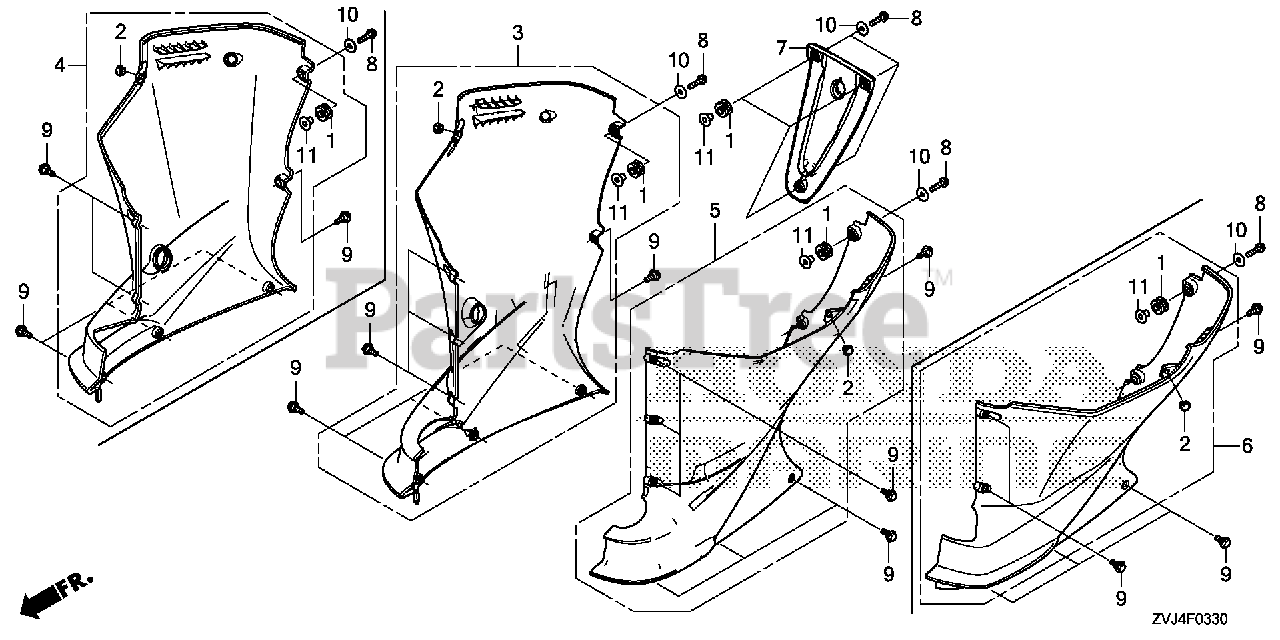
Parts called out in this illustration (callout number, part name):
1	GROMMET, CASE (LOWER)
2	RUBBER, STOPPER
4	COVER, R. ENGINE (LOWER) *NH565* (L) (GRAND PRIX WHITE)
4	COVER, R. ENGINE (LOWER) *NHB14M* (L) (AQUA MARINE SILVER METALLIC)
6	COVER, L. ENGINE (LOWER) *NH565* (L) (GRAND PRIX WHITE)
6	COVER, L. ENGINE (LOWER) *NHB14M* (L) (AQUA MARINE SILVER METALLIC)
7	COVER, RR.
8	BOLT, FLANGE (6X25)
9	BOLT, SPECIAL (6X17)
10	WASHER, PLAIN (6MM)
11	COLLAR (12X6.5)
